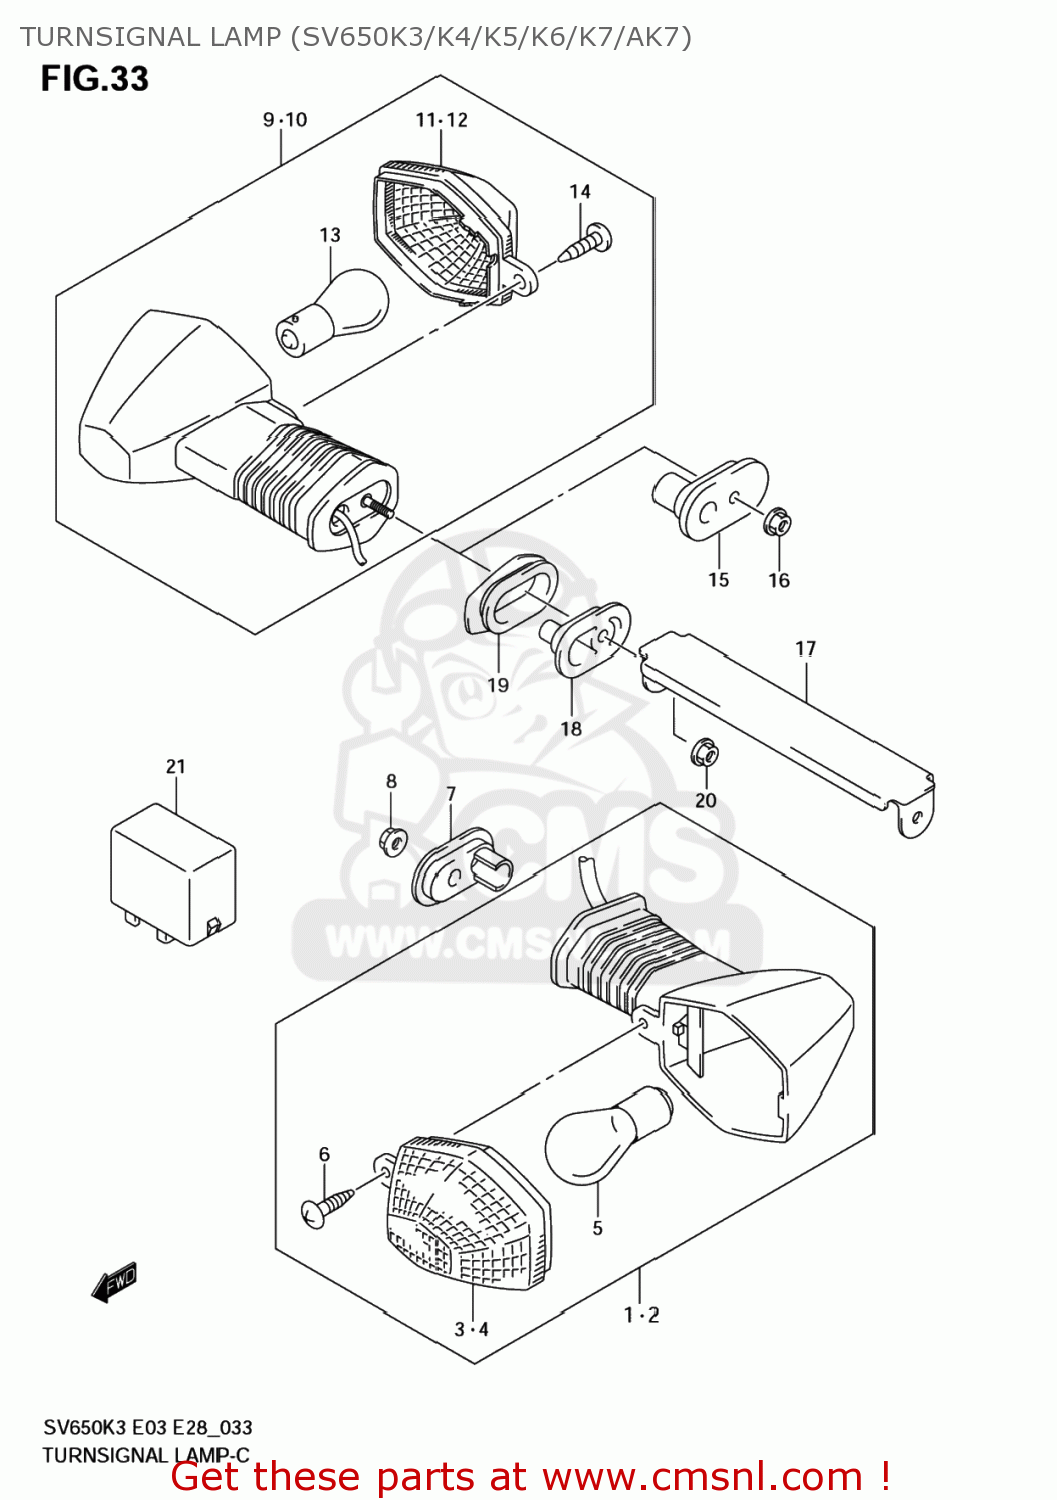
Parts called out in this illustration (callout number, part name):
1	LAMP ASSY,FR TURN SIGNAL,R
2	LAMP ASSY,FR TURN SIGNAL,L
3	LENS
4	LENS
5	BULB(12V21W)
6	SCREW
7	PLATE,TURNSIGNAL LAMP
8	NUT
9	LAMP ASSY,RR TURNSIGNAL,R
10	LAMP ASSY,RR TURNSIGNAL,L
11	LENS
12	LENS
13	BULB(12V21W)
14	SCREW
15	PLATE,TURNSIGNAL LAMP
16	NUT
17	BRACKET,RR TURNSIGNAL
18	PLATE,RR TURN SIGNAL
19	CUSHION,RR
20	NUT
21	RELAY ASSY,TURNSIGNAL LAMP
